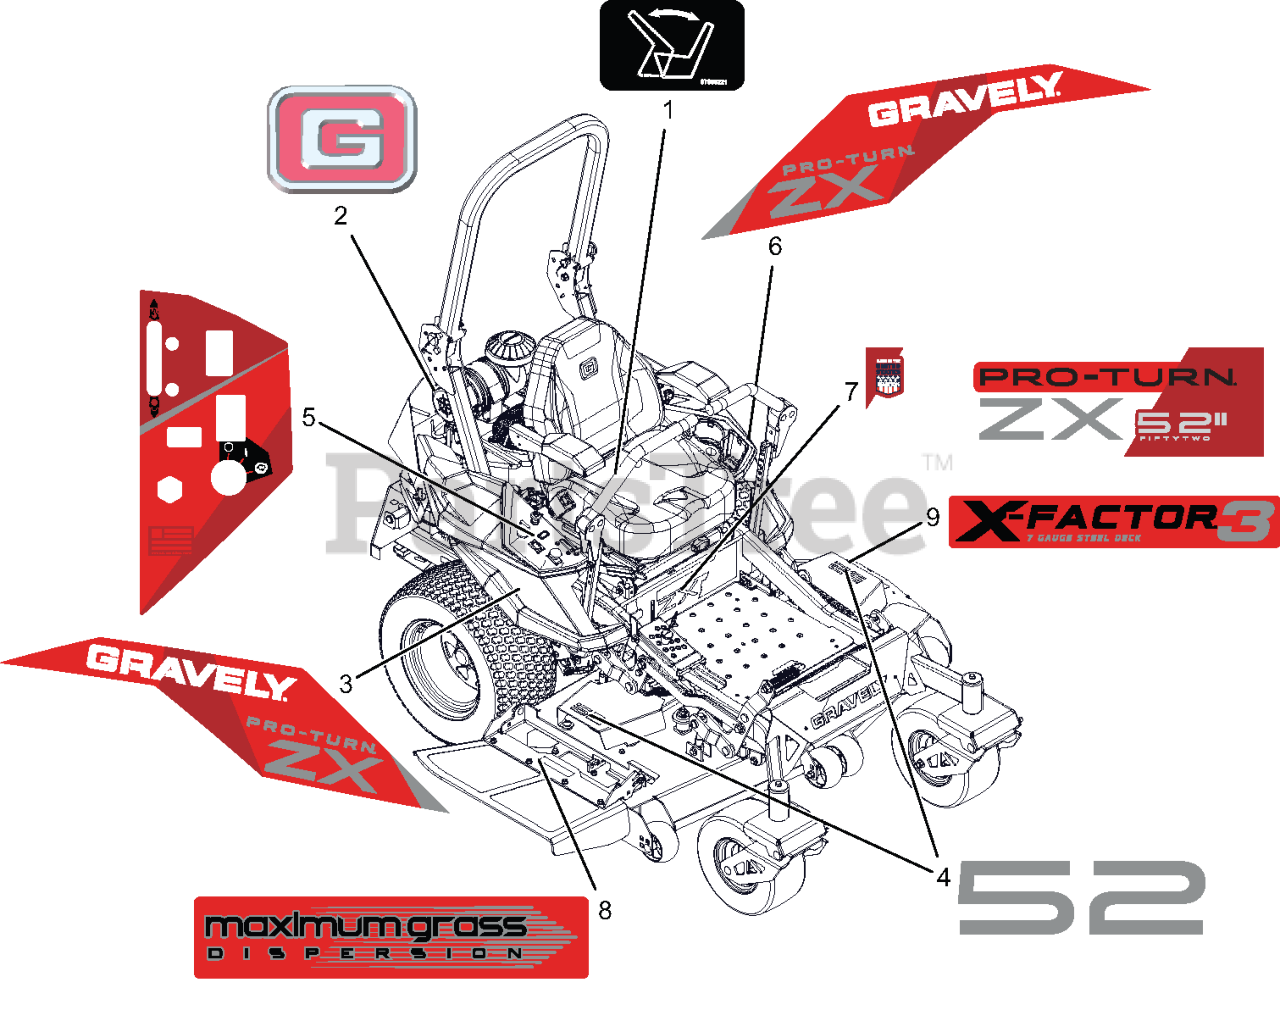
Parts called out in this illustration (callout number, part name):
1	DECAL - SEAT RELEASE
2	DECAL, GRAVELY BRAND
3	DECAL, FENDER RH - PTZX
4	DECAL, DECK - 52
5	DECAL, CONTROL PANEL
6	DECAL, FENDER LH - PTZX
7	DECAL, PTZX - 52
8	DECAL, DECK - MAX GRASS
9	DECAL, DECK - X-FACTOR 3 7 GAUGE
